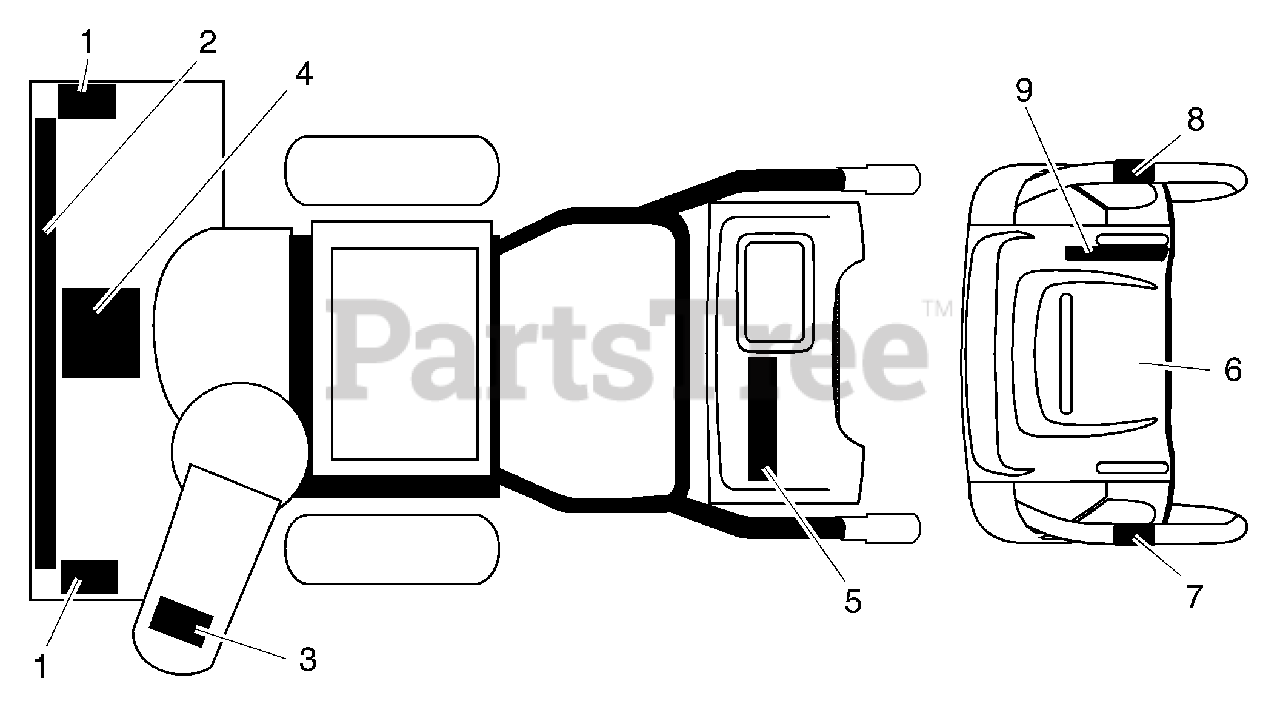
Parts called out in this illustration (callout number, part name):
1	Decal, Danger
2	Decal, Poulan Pro, 5HP / 24" (large)
3	Decal, Danger, Deflector
4	Decal, Danger
5	Decal, Poulan Pro, 5HP / 24" (small)
6	Decal, Instruction
7	Decal, Traction Lever
8	Decal, Auger Lever
9	Decal, Speed Control
